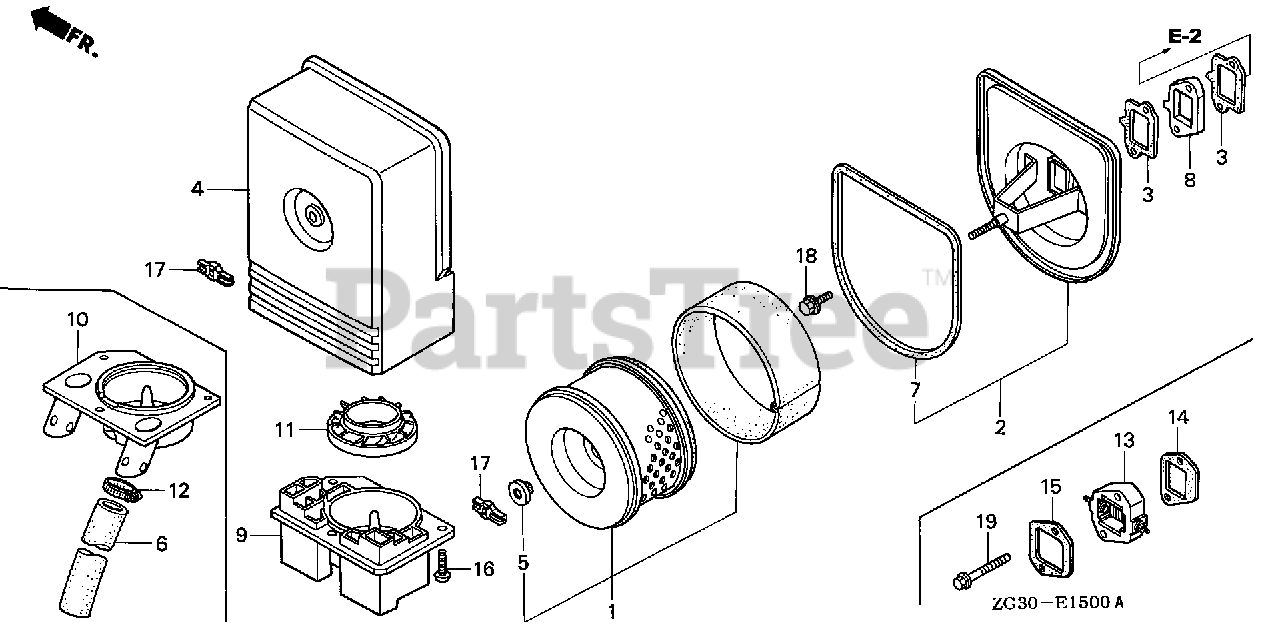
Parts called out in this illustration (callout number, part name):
1	ELEMENT, AIR CLEANER
2	HOUSING, AIR CLEANER
3	GASKET, AIR CLEANER (NON-ASBESTOS)
4	COVER, AIR CLEANER
5	GROMMET, AIR CLEANER
7	GASKET, AIR CLEANER HOUSING
9	CASE, PRE CLEANER
11	GUIDE, PRE AIR CLEANER
16	SCREW, PAN (5X16.5)
17	NUT, AIR CLEANER COVER (DACRO COATING)
18	BOLT, FLANGE (8X22)
